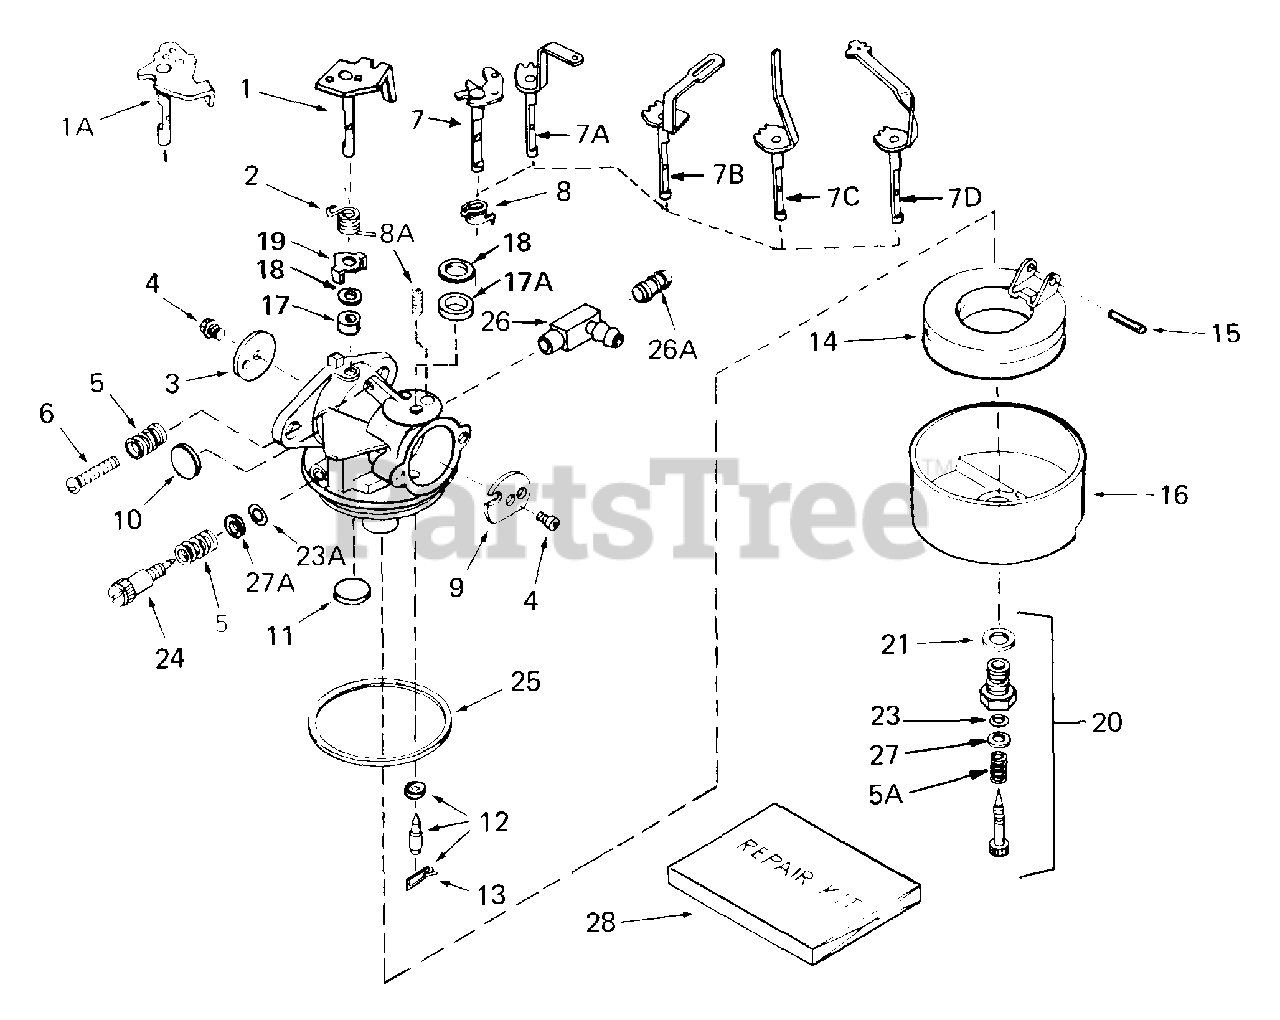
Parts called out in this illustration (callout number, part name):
1	"Shaft & Lever Assy., Throttle
2	Spring, Throttle return
3	Shutter, Throttle
4	Screw, Throttle & choke shutter
5	Spring, Regulating screw
5A	Spring, Main adi. screw
6	Screw, Idle regulating
7B	Shart & Lever Assy., Choke
8A	Spring, Choke positioning
9	Shutter, Choke
10	Plug, Welch
11	Plug, Welch
12	Inlet Needle, Seat & Clip Assy.
13	Clip, Inlet needle
14	Float, Carburetor
15	Shaft, Float
16	Bowl, Float
20	Adj. Screw Assy., Main
21	Gasket, Bowl-to-body
23	"O" Ring, Adj. screw
24	Screw, Idle adj.
25	Gasket, Bowl-to-body
26A	Fitting, Fuel inlet
28	Repair Kit
